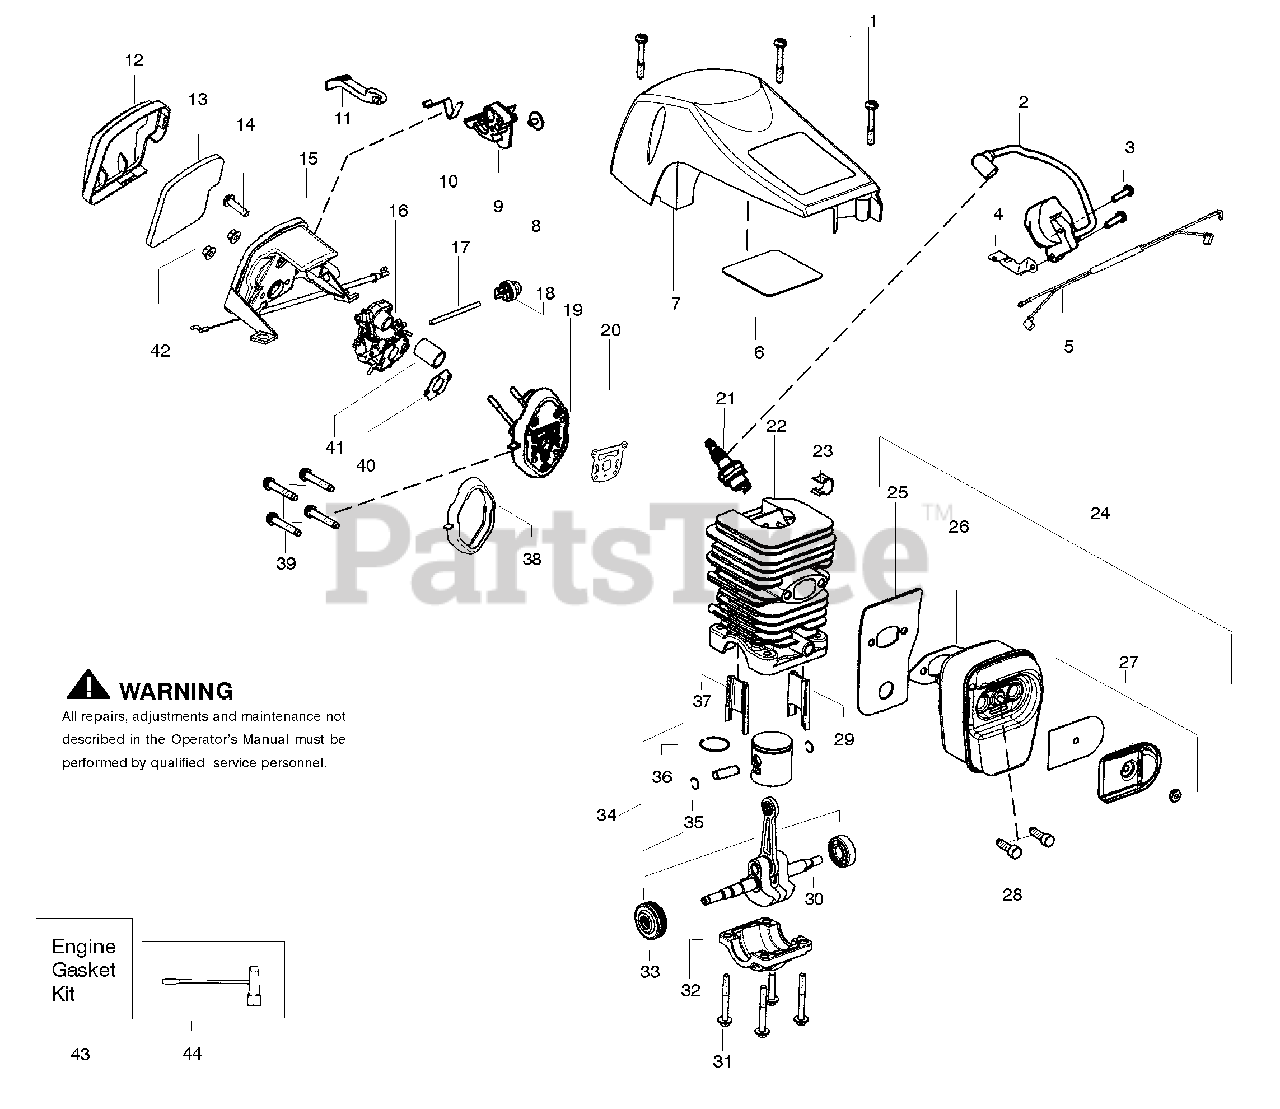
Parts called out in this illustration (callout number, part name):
2	Module-Ignition
4	Strap-Ground
5	Assy-Wire Harness
6	Reflector-Tape
7	Shield-Cylinder
9	Lever-Ignition Switch
10	Spring-Ignition Switch
11	Knob-Choke
12	Cover-Air Filter
13	Filter-Air
15	Housing-Air Filter w/cable
16	Carburetor Zama W26B
17	Kit-Fuel Line
18	Bulb-Purge "snap-in"
19	Kit-Carb. Adaptor
20	Gasket-cyl. o-ring
21	Accy-Spark Plug
22	Kit-Cylinder
23	Clip-High Tension Lead
24	Kit-Muffler
25	Backplate-Muffler
26	Gasket-Muffler
27	Kit-Spark Arrestor
28	Bolt-Muffler
29	Insert-Left Cyl.
30	Assy-Crankshaft/Rod
32	Cap-Crankcase
33	Assy-Bearing/Seal
34	Kit-Piston
35	Retainer-Piston Pin
36	Ring-Piston
37	Insert-Right Cyl.
38	Seal-Adaptor
40	Gasket-Carb.
41	Tube-Intake
42	Nut-Carb.
43	Kit-Gasket
44	Scrench
